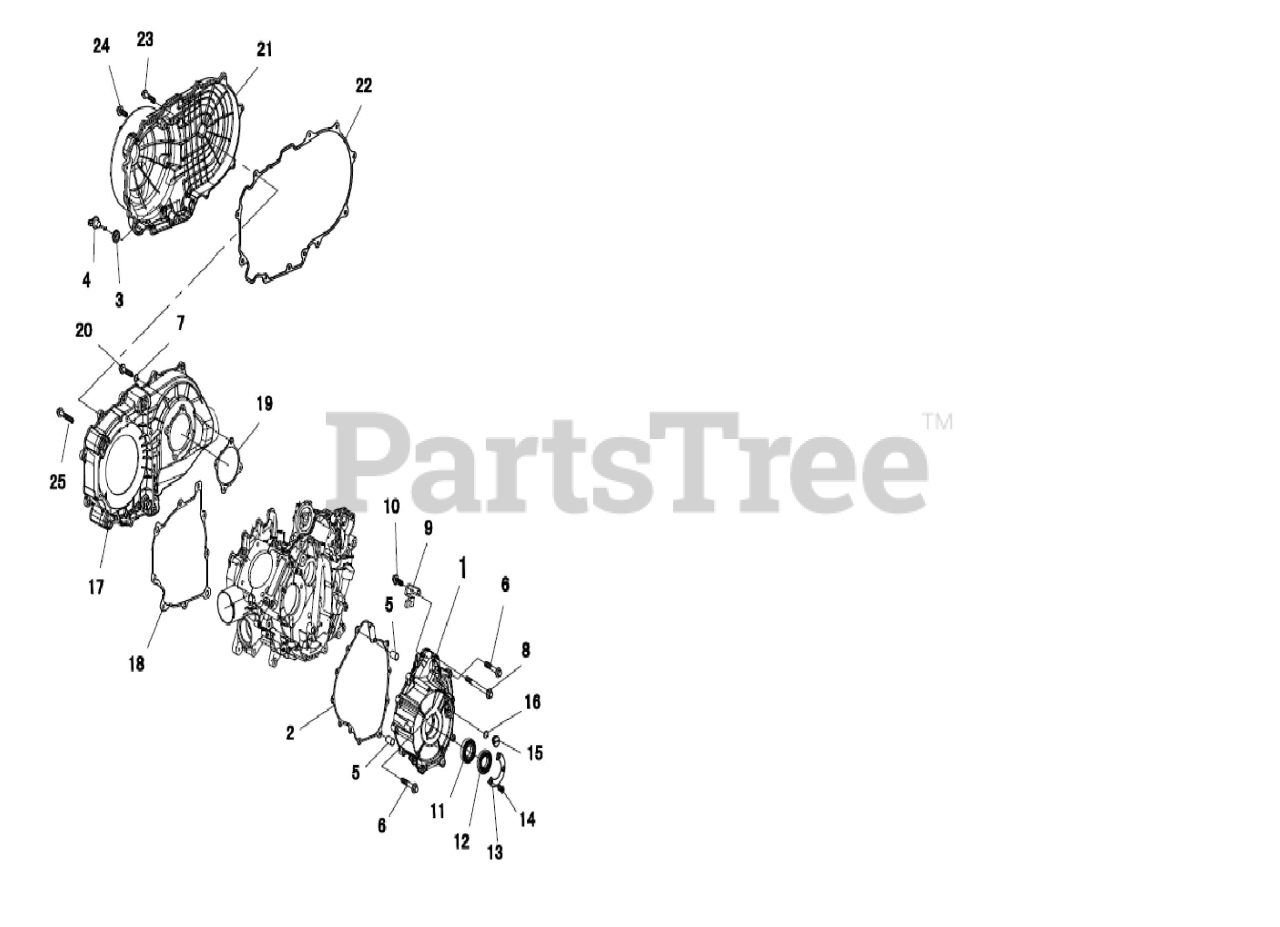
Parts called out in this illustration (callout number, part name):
1	Left Crankcase Cover
2	Gasket,Left Crankcase Cover
4	Plug,Clutch Cover
5	Pin,Dowel 10X16
6	Hex flange bolts M6X30
7	Spring Washer 6
8	Hex flange bolts M6X40
9	Stator wire guard plate
10	Hex flange bolts M6X12
11	Bearing 60/28
12	Oil Seal 28X52X8.5
13	Press Plate,Oil Seal
14	Cross recessed countersunk head screw M5X12
15	Small Peep Hole Cover
16	O-Ring 13.4X2.35
17	Cover,Clutch,Inner
18	Seal,Clutch Inner Cover ?
19	Seal,Clutch Inner Cover ?
20	Hex flange bolts M6X32
21	Cover,Clutch,Outer
22	Seal,Clutch Cover
23	BOLTS HEXAGON FLANGE M6 X 25
24	Hex flange bolts M6X16
25	Hex flange bolts M6X50
